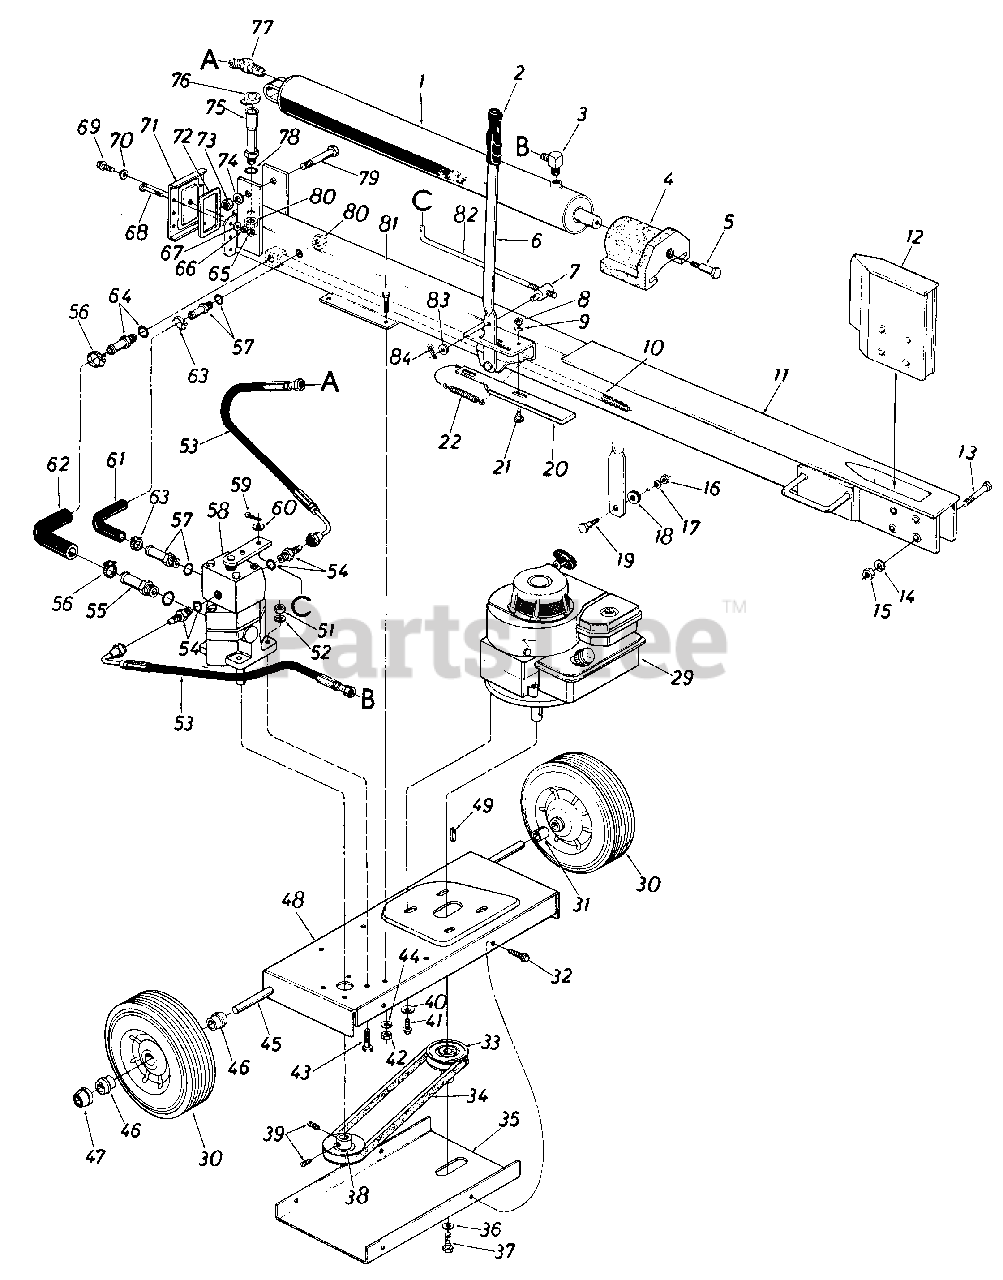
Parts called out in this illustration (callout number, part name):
1	CYLINDER-HYDRO
2	GRIP-LIFT HANDLE
3	ADAPTER-90 DEGREE
4	PLATE-PUSH
5	SCREW-SHLD .62X.475
7	FERRULE-ADJ
8	NUT-HEX 5/16-18
9	WASHER-LOCK-5/16
10	TUBE ASSY-STRAINER
11	TANK ASSY-OIL
12	WEDGE ASSY
13	SCREW-HEX 5/8-18 X 3.50
14	WASHER-LOCK-5/8
15	NUT-HEX 5/8-18
16	NUT-HEX 3/8-16
17	WASHER-LOCK-3/8
18	WASHER-RUBBER .50 X 1.00 X .25
19	SCREW-SHLD .498 DIA X .340
20	BRACKET-ENGAGE
21	SCREW-SHLD .437 DIA X .180
22	SPRING-EXTENSION
30	WHEEL ASSY W/TIRE-10 X 2.75
31	SLEEVE
32	SCREW-HEX WASH SF TAPP
34	BELT-V 1/2 X 30
35	COVER-BELT
36	WASHER-LOCK-5/16
37	BOLT-3/8 NF X 1"GR5
39	SCREW-SET 1/4-28 X .25
40	BODY-BOTTOM
41	SCREW-HEX WASH HD 3/8-24 X 7/8
42	NUT-5/16-24
43	SCREW-HEX 5/16-18 X 1.00
44	WASHER-LOCK-5/16
45	SHAFT-AXLE
46	BEARING-FLANGE
48	FRAME-MOTOR 120 V
49	KEY-SQ 3/16X1.50
51	NUT-HEX 5/16-18
52	WASHER-LOCK-5/16
53	HOSE-PRESSURE
56	CLAMP-HOSE-5/8
58	PUMP ASSY
59	PIN-COTTER-3/32 DIA X .75
60	WASHER-FL-.344 X .62
61	HOSE-RETURN-90 DEG
62	HOSE-SUCTION-90 DEG
63	CLAMP-HOSE 1/4 ID
65	NUT-HEX 5/16-18
66	WASHER-LOCK-5/16
67	WASHER-FL (#46041)
68	SCREW-HEX 5/16-18 X 1.50
69	SCREW-HEX WASH HD 5/16-18
70	WASHER-GASKET
71	PLATE-END
73	NUT-HEX 3/4
74	WASHER
75	TUBE ASSY-FILLER
76	CAP ASSY-GAS
77	ADAPTER-45 DEGREE
79	SCREW-HEX 3/4X4.0
80	NUT-HEX 1 1/16-12
81	SCREW-HEX SPECIAL 5/16-24X1.0
82	ROD-ENGAGEMENT
83	WASHER-FL-.344 X .62
84	PIN-INTERN COT-5/16 DIA
